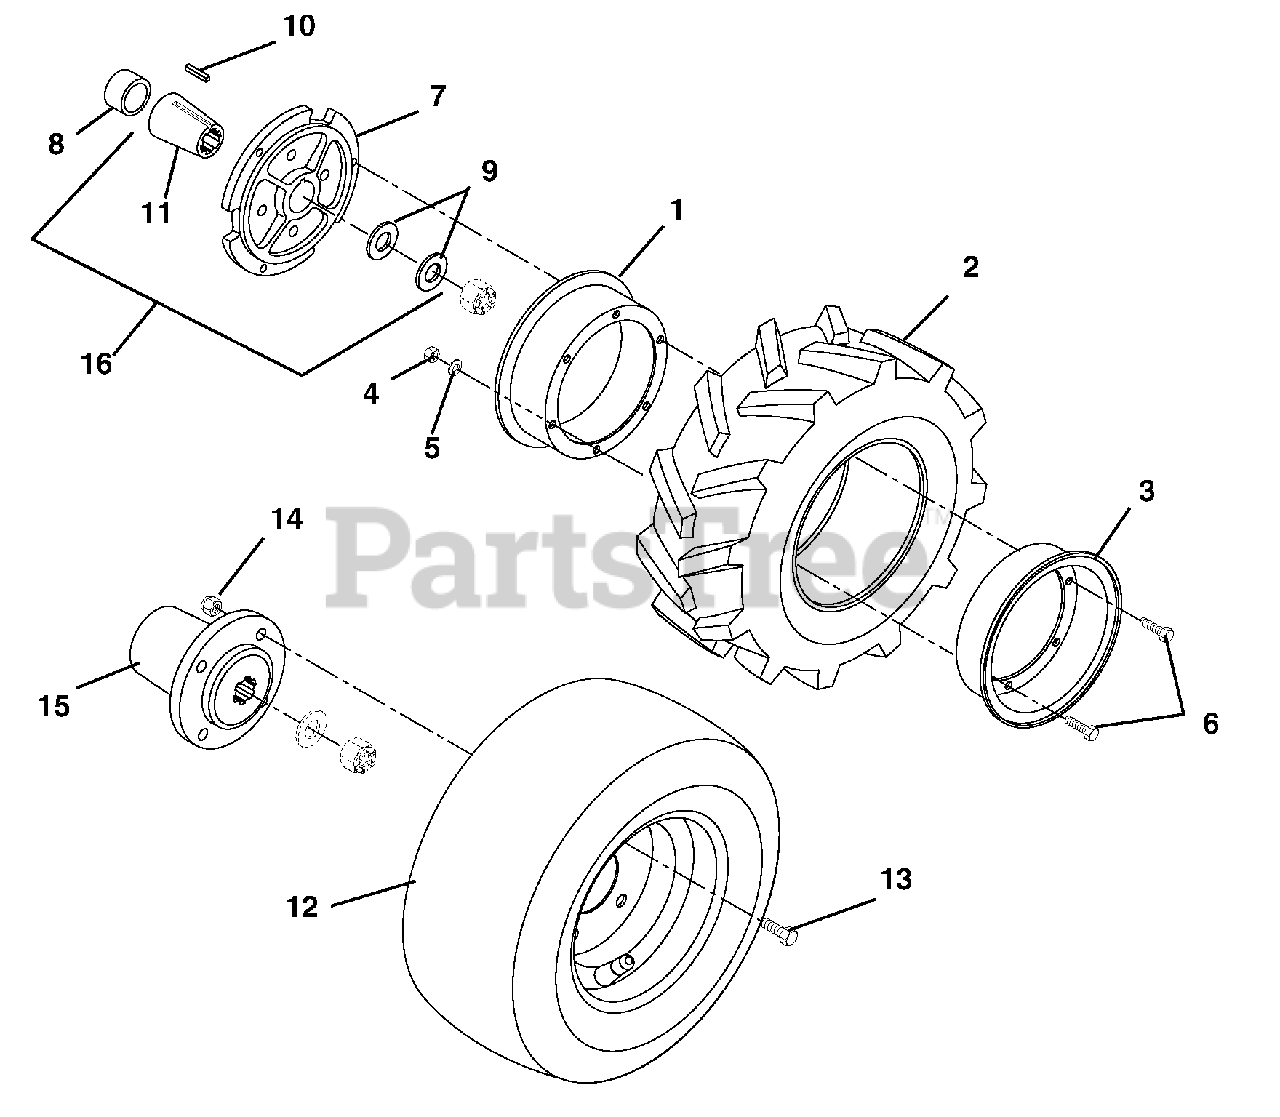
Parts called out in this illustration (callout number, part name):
1	Wheel 7.71 x 1.25
2	Tire 16 x 5W x 3
3	Wheel-Disc 6.75 x 9.219
4	Nut-Hex .38-16
5	Washer-Lock .375 x .094
6	Bolt-Hex .38-16 x .75 Grade 5
7	Hub-Wheel
8	Bushing-Sleeve 1.02 x 1.37 x 1.13
9	Washer-Flat-Steel .812 x 2.00 x .148
10	Key-Square .249 x 1.25 x .248
11	Insert-Hub
12	Tire/Wheel Assembly 8.50-8 x 18
12	Tire/Wheel Assembly 4.80/4.00-8
12	Tire/Wheel 4.80/4.00-8 R.H.
12	Tire/Wheel 4.80/4.00-8 L.H.
13	Bolt-Hex .50-13 x 1.50 Grade 5
14	Nut-Locking-Center .50-13 Grade 5
15	Hub-7" Wheel
16	Kit, Heavy Duty Hub
